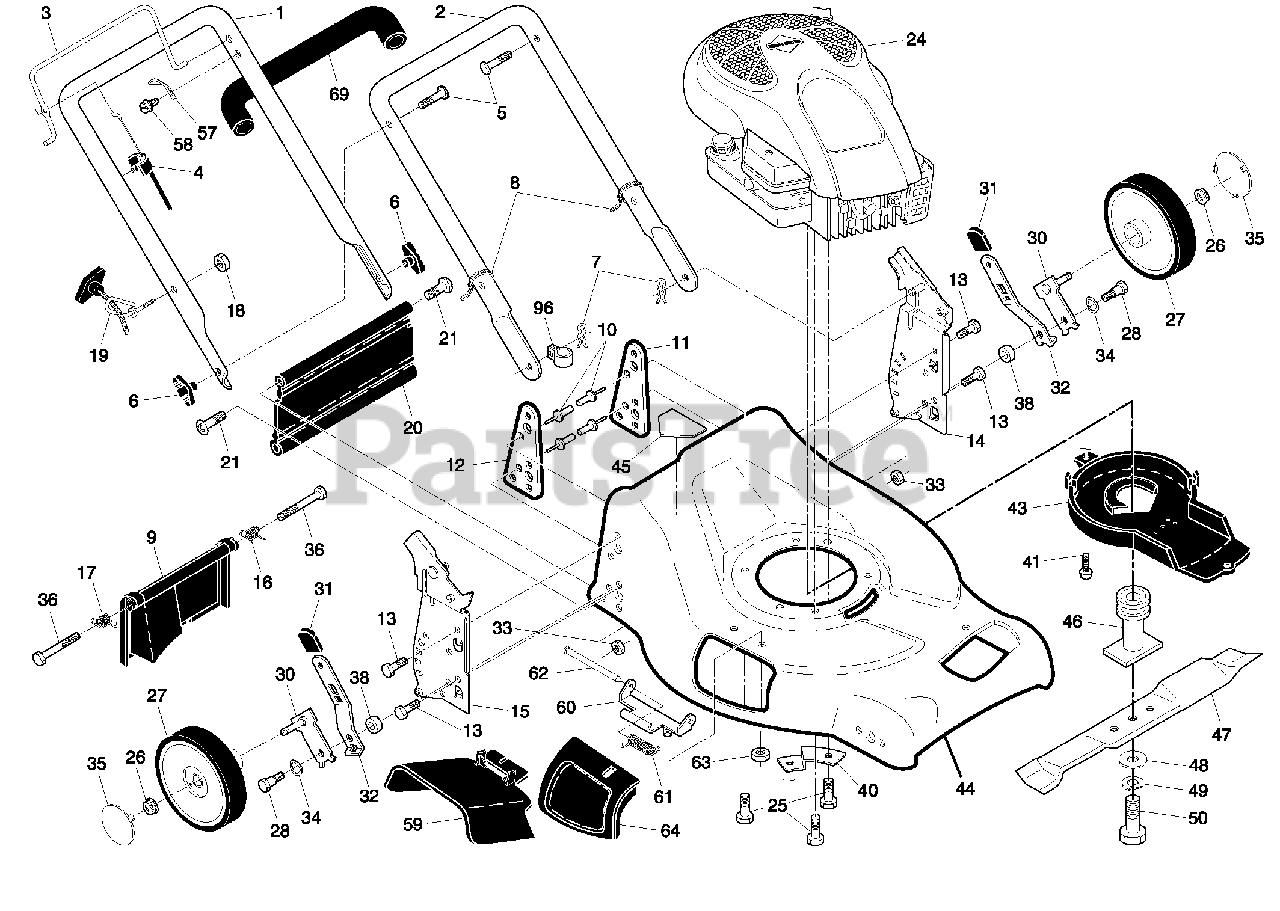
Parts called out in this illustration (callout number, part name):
1	Upper Handle Assembly
2	Lower Handle
3	Control Bar
4	Engine Zone Control Cable
5	Handle Bolt
6	Handle Knob
7	Hairpin Cotter
8	Wire Tie
9	Rear Door Assembly
10	Pop Rivet
11	Support Bracket, LH
12	Support Bracket, RH
13	Screw, Tapping 1/4-20 x 5/8
14	Handle Bracket, LH
15	Handle Bracket, RH
16	Spring, Rear Door, LH
17	Spring, Rear Door, RH
18	Nut, Hex 1/4-20
19	Rope Guide
20	Rear Skirt
21	Hinge Screw 1/4-20 x 1-1/4
25	Hex Head Thread Rolling Screw 3/8-16 x 1-1/8
26	Hex Flange Nut
27	Wheel & Tire Assembly
28	Shoulder Bolt 5/16-18 x 1-21/64
30	Axle Arm Assembly, Rear
31	Selector Knob
32	Selector Spring
33	Nut, Hex
34	Washer, Curved, Cylindrical
35	Hubcap
36	Bolt, Rear Door
38	Spacer
40	Mounting Bracket, Debris Shield
41	Screw, Debris Shield
43	Debris Shield
44	Kit, Lawn Mower Housing
45	Danger Decal
46	Blade Adapter / Pulley
47	Blade, 21"
48	Hardened Washer
49	Helical Washer
50	Screw, Hex Head, Grade 8, 3/8-24 x 1-3/8
57	Bracket, Upstop
58	Screw #10-24 x 1/2
59	Discharge Deflector
60	Hinge Bracket
61	Hinge Spring
62	Hinge Rod
63	Nut, Hex
64	Mulcher Door
69	Foam Grip
96	Clip, Cable
96	Operator's Manual, English
96	Operator's Manual, French
96	Replacement Parts Manual
